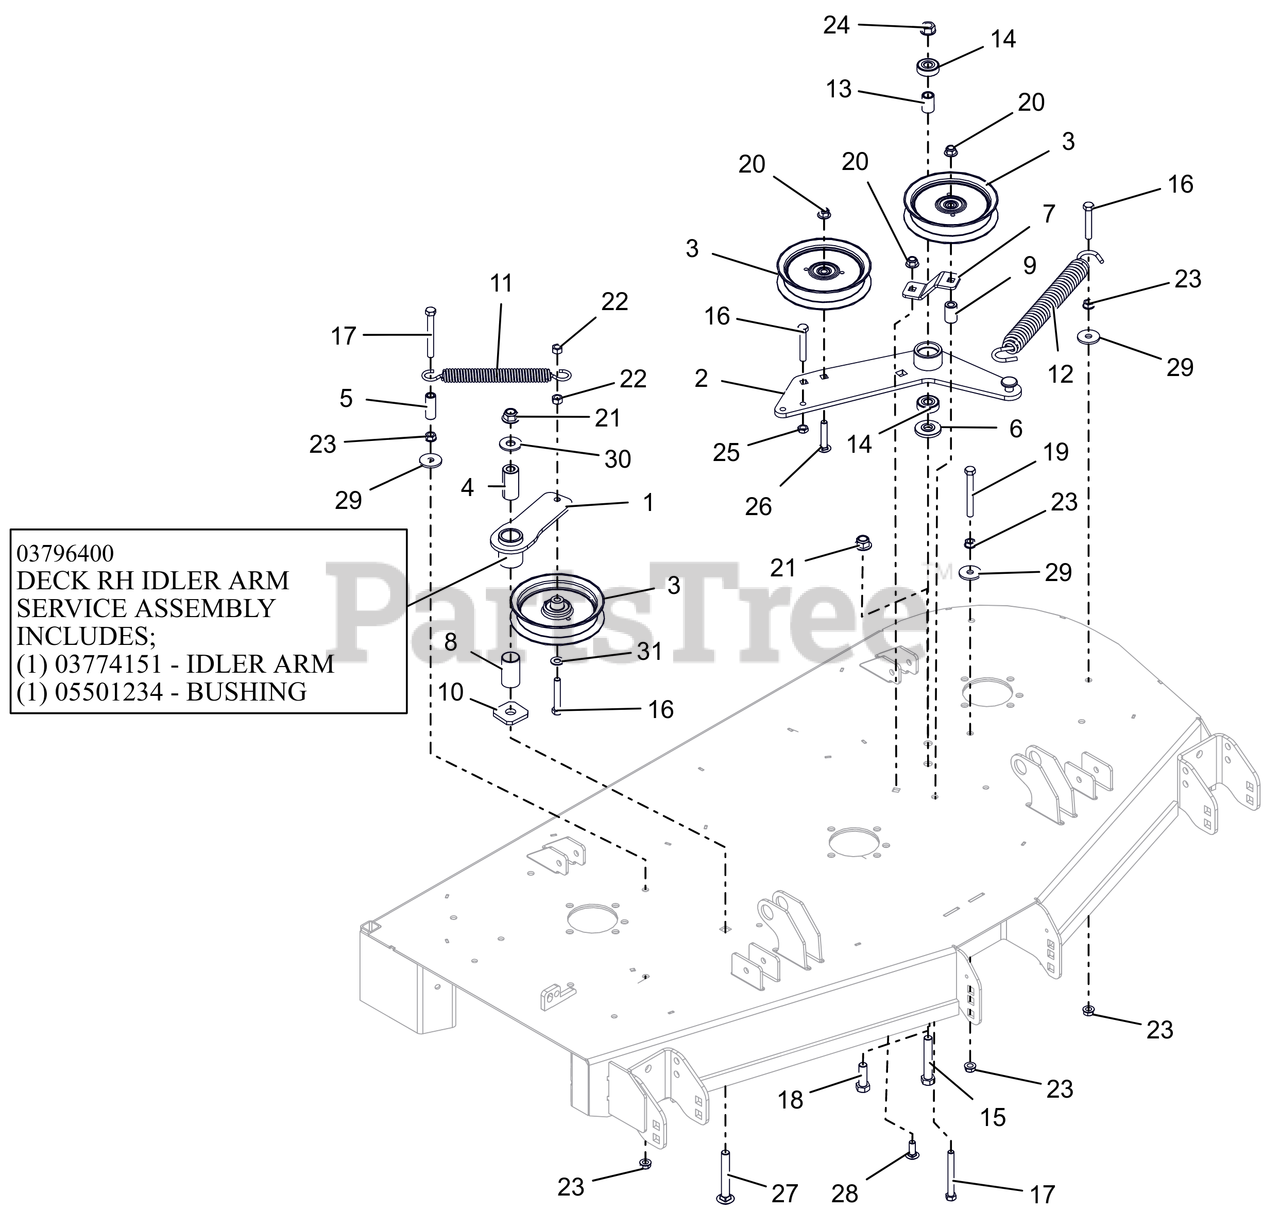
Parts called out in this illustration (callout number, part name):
1	WMT, IDLER ARM - BLACK
1	ASM, IDLER ARM (DECK)
2	DECK PTO IDLER ARM WLDMT - BLK
3	IDLER, FLAT 5.00"
4	BSHG, SPCR .502X.997X2.03 PM
5	SPACER, .375IDX.625ODX1.66 PM
6	SPACER, IDLER ARM
7	PTO FIXED IDLER MTG BRKT -RED
8	BSHG, 1.00X1.125X1.937
9	BUSHING, SLV .380X.750X1.190
10	WSHR-FLT .640X1.75X.250
11	SPRING, EXTENSION
12	SPRING, EXTENSION
13	SPACER .510 X .75 X 1.1485
14	BRG-BALL .500X1.38X.437
15	BLT, HEX .50-13X3.00 G5 ZCC
16	BLT,HEX .38-16X2.25 G5 ZCC
17	BLT, HEX .38-16X3.25 G5 ZCC
18	BLT,HEX .50-13X1.50 G5 ZCC
19	BLT, HEX .38-16X3.25 G5 ZCC
20	NUT,NYL-FLG .38-16 GF ZCC
21	NUT,NYL-FLG .50-13 GF ZCC
22	NUT-LK-CTR .38-16 ZC120
23	NUT, SPNLK-FLG .38-16 G5 ZCC
24	NUT-LK-CTR-FLG .500-13 GG ZCC
25	NUT-JAM .375-16 G2 ZCC
26	BLT,RHSSN.375-16X2.00 G5 ZCC
27	BLT, RHSN .50-13X3.50 G5 ZCC
28	BLT,RHSSN .38-16X1.00 G5 ZCC
29	WSHR,FLT .406X1.375X.135 ZCC
30	WSHR,FLT .563X1.375X.109 ZCC
31	WSHR,FLT .406X.812X.065 ZCC
